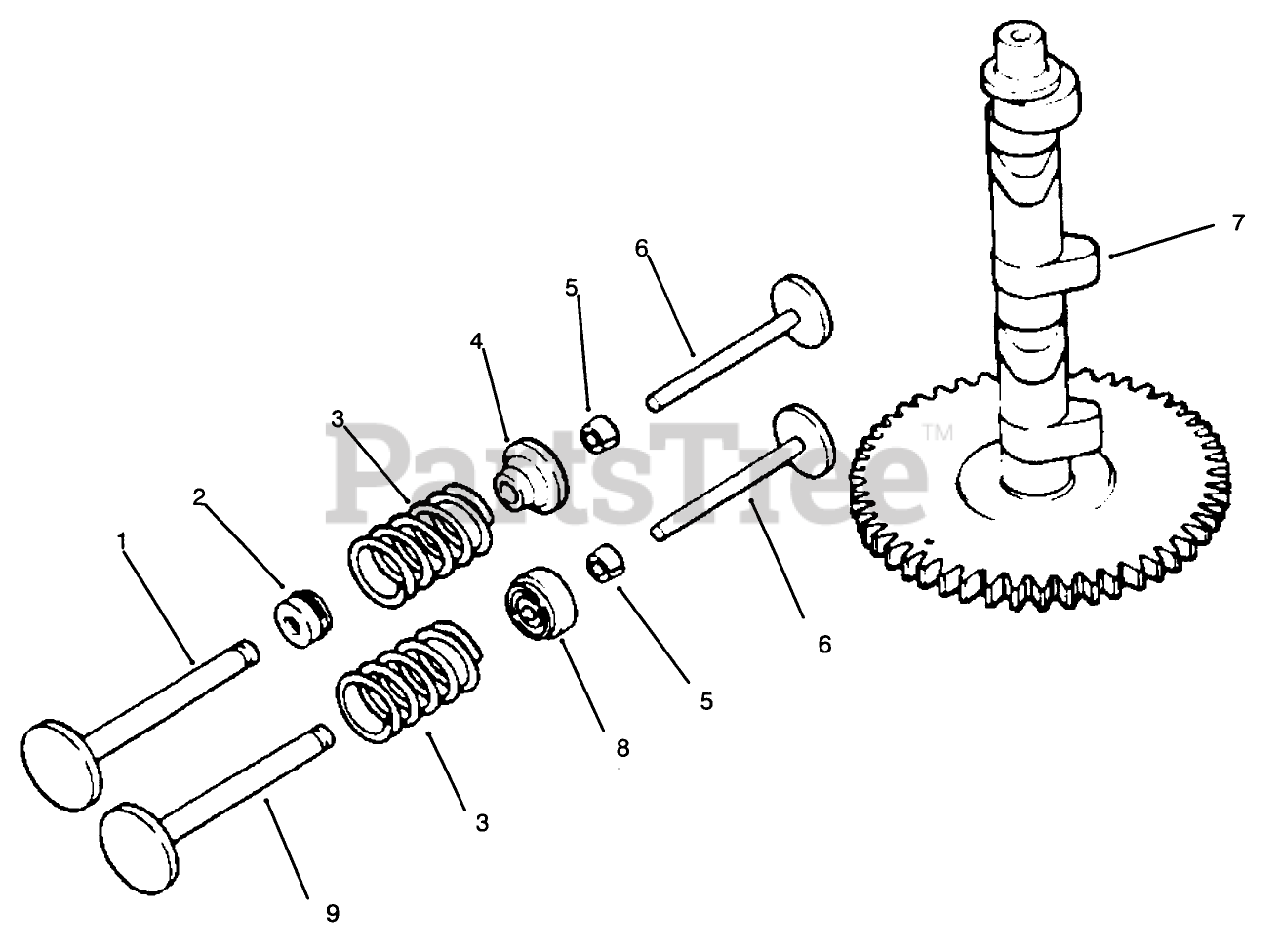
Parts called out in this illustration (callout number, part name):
1	Valve-Intake
2	Seal-Intake Valve Stem
3	Spring-Valve
4	Retainer-Spring
5	Kit-Retainer
6	Tappet
7	Camshaft
8	Rotator-Valve
9	Valve-Exhaust
